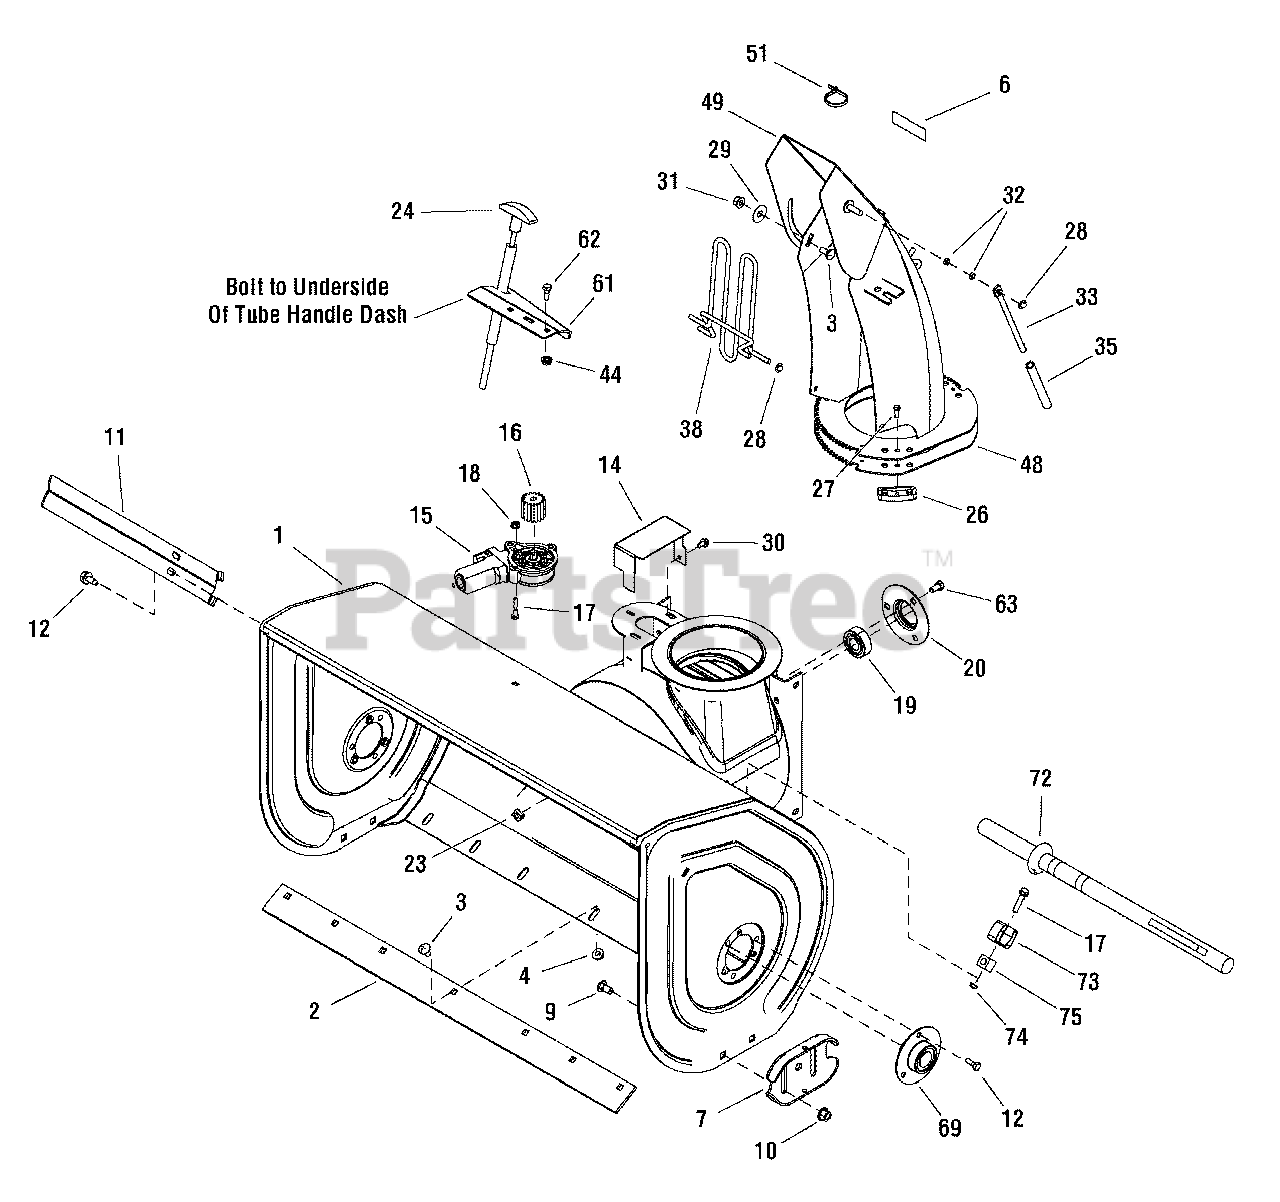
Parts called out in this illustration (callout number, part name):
1	HOUSING ASSEMBLY, 38"
2	BLADE, Scraper 38"
3	CARRIAGE BOLT, 5/16-18 x 3/4, G5
4	NUT, Hex Lock Flange, 5/16-18
6	DECAL, Red Strip
7	SKID SHOE
9	BOLT, Carriage, 3/8-16 X 1
10	NUT, Hex Flange 3/8-16 ESNA
11	CUTTER, Drift
12	SCREW, Hex Washer Head Taptite, 5/16-18 x 3/4
14	COVER, Gear 38"
15	MOTOR, Spout Rotator 38"
16	PINION, 1.417OD .296 Slot, 1-1/4 LG, 16T Powdered Metal
17	CAPSCREW, Hex Washer, #10 x 1-1/4
18	NUT, Hex Whiz Lock Flange, 10-24
19	BEARING, 3/4 ID x 1.78 OD x .61 LG Greased
20	RETAINER, Bearing
23	RETAINER, Nut, 5/16-18 .057/.092
24	CABLE & KNOB ASSEMBLY
26	HOLD DOWN, Chute Black Nylon
27	SCREW, Hex Washer Head Plastite, 10-14 x 5/8
28	NUT, Push Pal, 1/4 DIA Stud Capped
29	WASHER, Nylon, .388 x 1.12 x .03
30	SCREW, Hex Washer Head Taptite, 1/4-20 x 3/8
31	NUT, Hex Flange, 5/16-18 ESNA
32	SPACER
33	ROD, 5/16 DIA 5.88 LG
35	SPRING, Compression
38	GUARD & SUPPORT ASSEMBLY, Chute
44	NUT, Hex Keps, 1/4-20 Conical Washer
48	GEAR, Chute, 10 OD x 6.65 ID x .105 TH
49	CHUTE ASSEMBLY, 38"
51	TIE, Self Locking, .184 WD 7.31 LG
61	SUPPORT, Cable Tube Handles
62	CAPSCREW, Hex Head 1/4-20 x 3/4, G5
63	SCREW, Hex Whiz Lock Flange, 5/16-18 x 3/4
69	BEARING, Ball, 1.002 ID 2.049 OD 1.09 LG
72	STICK, Cleanout w/Brush, Snow
73	CLIP, Retainer
74	NUT, Hex Lock, 10-24 with Nylon Insert
75	BLOCK, Universal Pivot
